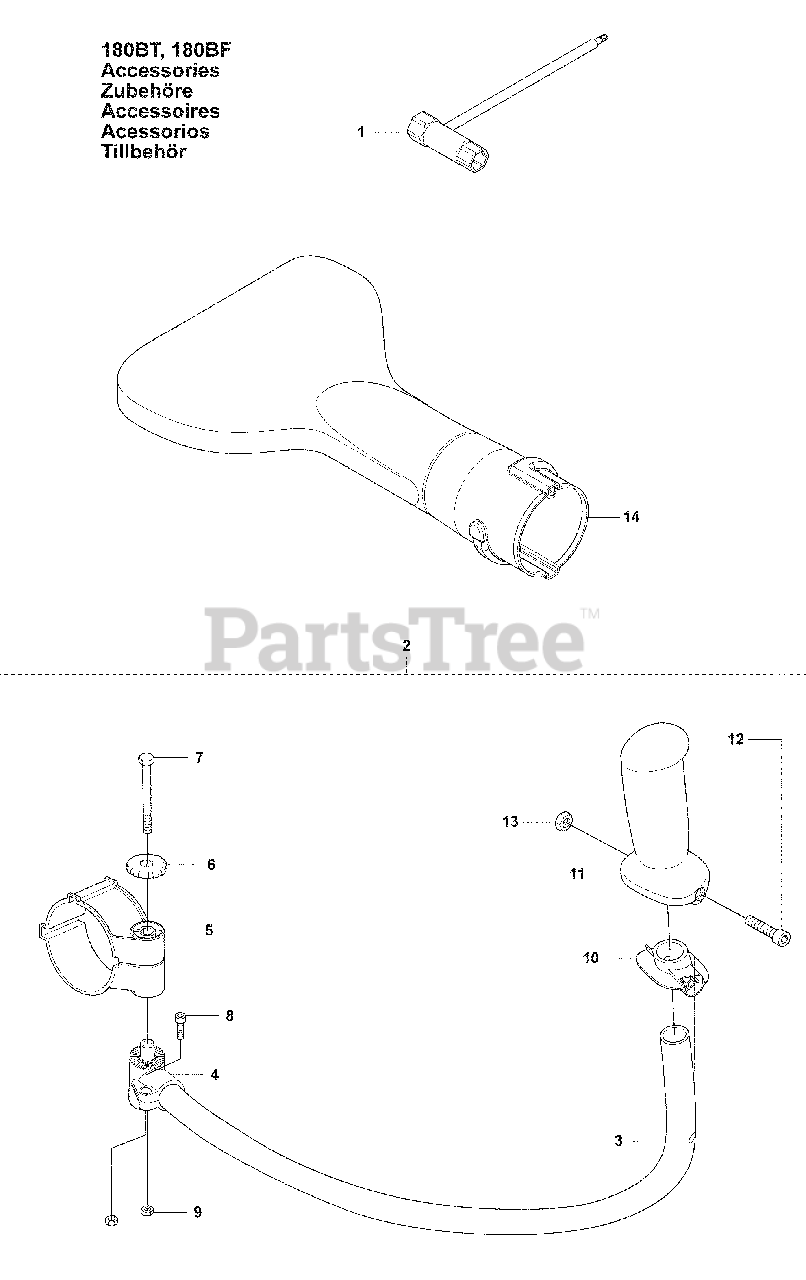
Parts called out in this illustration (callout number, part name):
1	SOCKET
2	Handle, 170 BT
5	HOLDER TH
6	Air Filter Cover Knob
8	Screw, MC6S 5 X 10
9	Hex Nut, M5 X .80 DIN
13	Hex Nut, M5 X .80 DIN
14	Flat Nozzle
